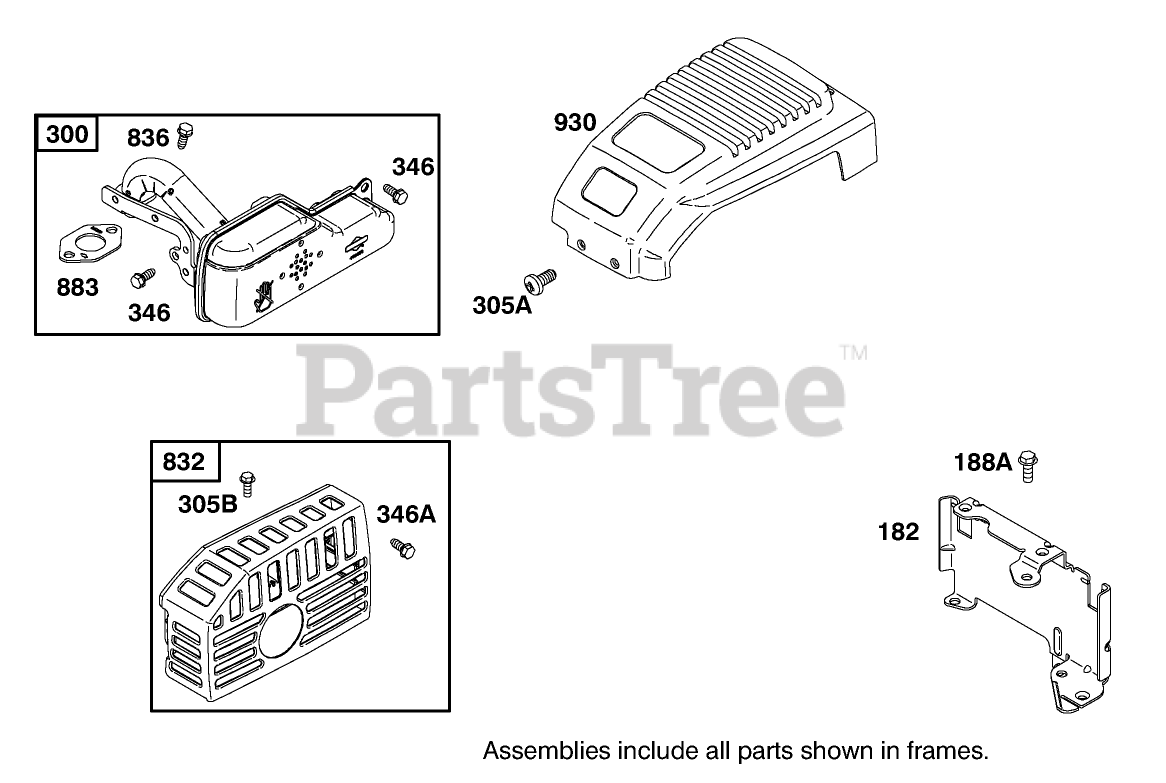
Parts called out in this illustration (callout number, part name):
182	BRACKET-TANK, FUEL
188A	SCREW-BRACKET, TANK
305B	HEX SCREW
346	SCREW-HH
346A	SCREW-HH
832	GUARD-MUFFLER
836	SCREW-HH
883	GASKET-EXHAUST
930	GUARD-REWIND
